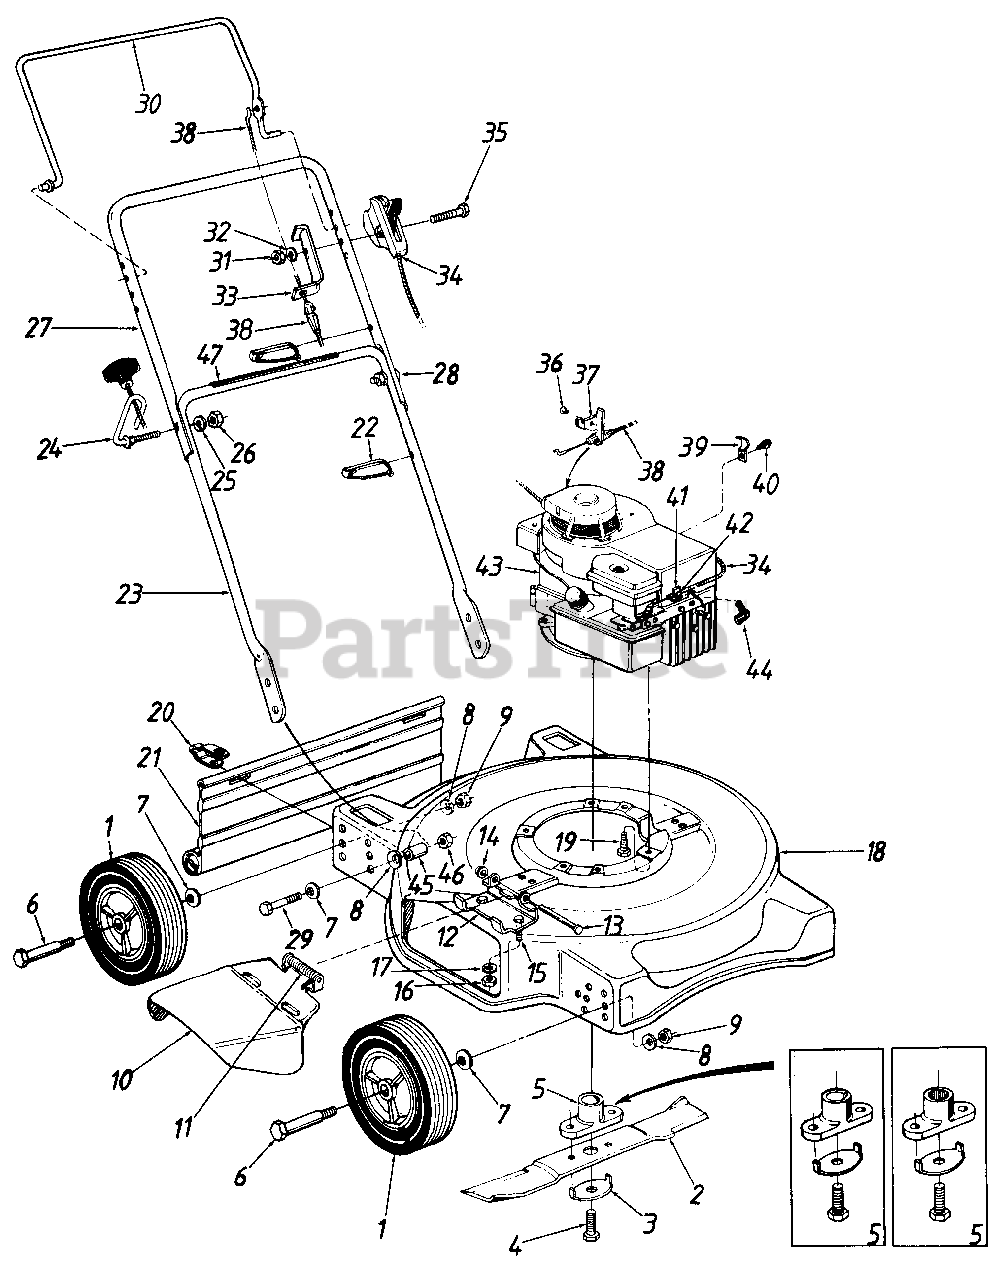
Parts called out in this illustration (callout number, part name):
1	Wheel Ass'y. Complete
2	20" Blade
3	Blade Bell-Wash. .45" I.D. x 2.38"
4	Hex Bolt 3/8-24 x 1.5" Lg.
5	Blade Adapter Kit Keyed
6	Shld. Bolt .498" Dia. x 1.64" Lg.
7	Bell-Wash. .380" I.D. x .88" O.D.
8	Bell-Wash. .39 I.D. x 1.13 O.D.
9	Hex Nut 3/8-16 Thd.*
10	Chute Deflector Ass'y.
11	Torsion Spring
12	Adapter Plate
13	Pivot Pin
14	Speed Nut 1/4" Rod
15	Hex Bolt 1/4-20 x .5" Lg.
16	Hex Nut 1/4-20 Thd.
17	L-Wash. 1/4" I.D.
18	20" Deck Ass'y.
19	Hex Wash. Hd. Scr. 3/8-16 x 1" Lg.
20	Hinge Clip
21	Rear Flap 16.75" Lg.
22	Cable Tie
23	Lower Handle
24	Rope Guide Bolt
25	L-Wash. 5/16" I.D.*
26	Hex Nut 5/16-18 Thd.*
27	Upper Handle
28	Curved Carriage Bolt 5/16-18 x 1.38" Lg.
29	Hex Bolt 3/8-24 x 1.5" Lg. Grade 5
30	Control Handle
31	Hex Nut 1/4-28 Thd.*
32	Spr. Wash. .265" I.D. x .562" O.D.
33	Cabie Mounting Bracket
34	Throttle Control Ass'y. Comp.
35	Hex Bolt 1/4-28 x 1.75" Lg.*
36	Pop Rivet .156" Dia. x .316
37	Cable Bracket
38	Control Cable-39"
39	Casing Clamp
40	Hex B-Tap Scr. #10 x .38" Lg.
41	Casing Clamp
42	Hex Wash. Hd. AB-Tap Scr. #8 x .50" Lg.
43	Engine
44	Spark Plug Boot
45	Spacer .381" I.D. x .56" O.D. x.75" Lg.
46	Hex Lock Nut 3/8-24 Thd.
47	Instruction Label-Handle
